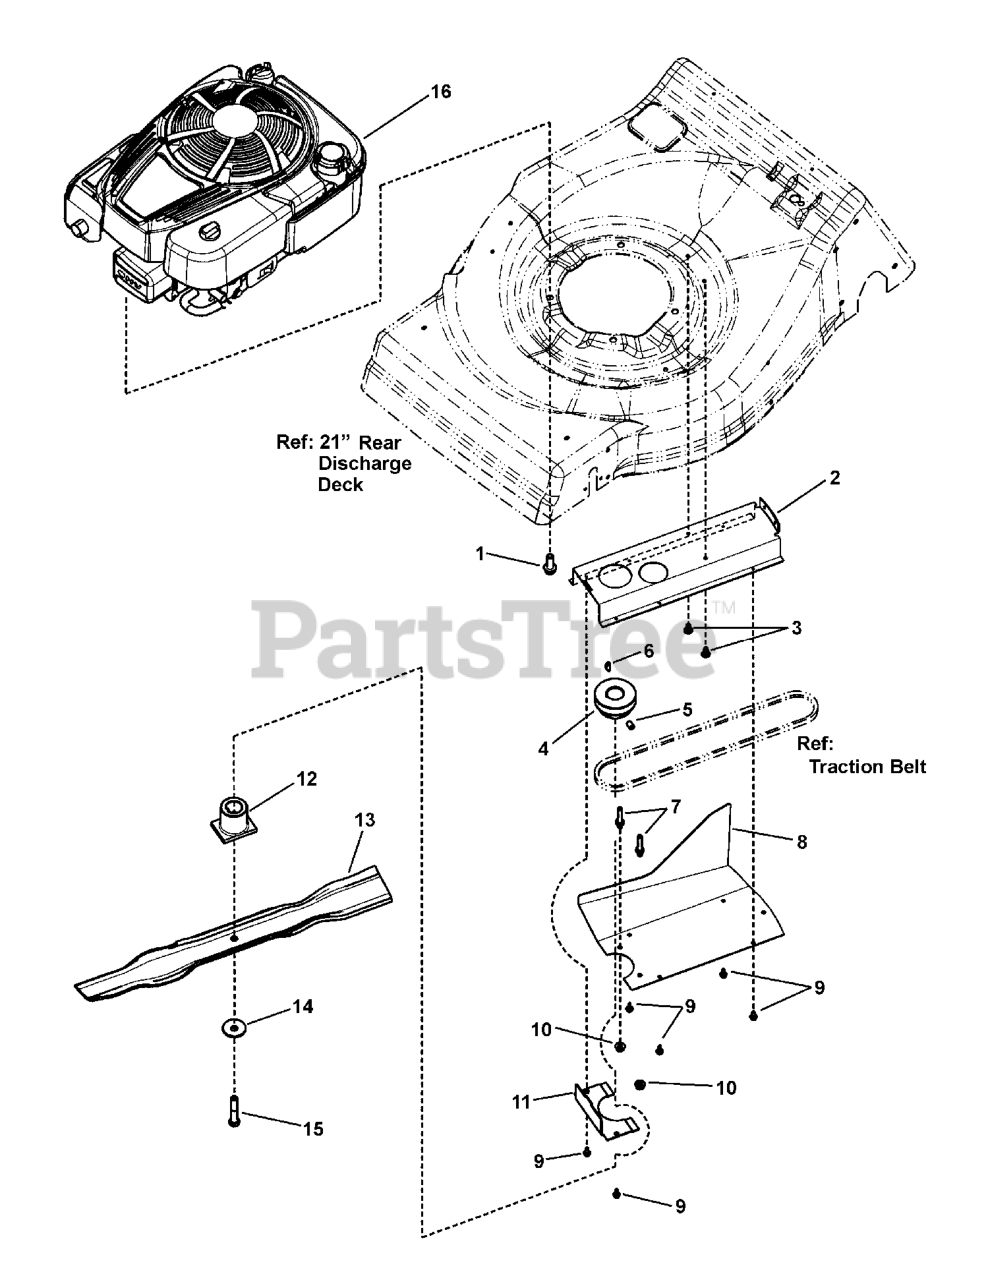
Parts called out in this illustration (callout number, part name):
1	SCREW, 3/8-16 x 1" Hex Washer Self-Tap
2	BELT GUARD
3	SCREW, 1/4-20 x .550 Torx Self-Tap
4	PULLEY, Engine
5	SET SCREW, 5/16-18 x 1/2" Hex Recess
6	KEY, #HP-506 Hi-Pro
7	BELT GUIDE, Engine, 21" RD (1/4-20 thread)
8	COVER, Belt Guard
9	SCREW, #10-16 x 1/2", AB, w/Washer
10	NUT, 1/4-20 Hex Flange Lock, YZ
11	COVER, Belt
12	BLADE HUB, 21" WBM, Rear Drive, 2 Position
13	BLADE, Wave, 21" Steel Deck
14	WASHER, Cone
15	SCREW, 3/8-24 x 2" Hex Head Cap, GR 5
16	* ENGINE, Briggs 875 Gross Professional Torque Series
